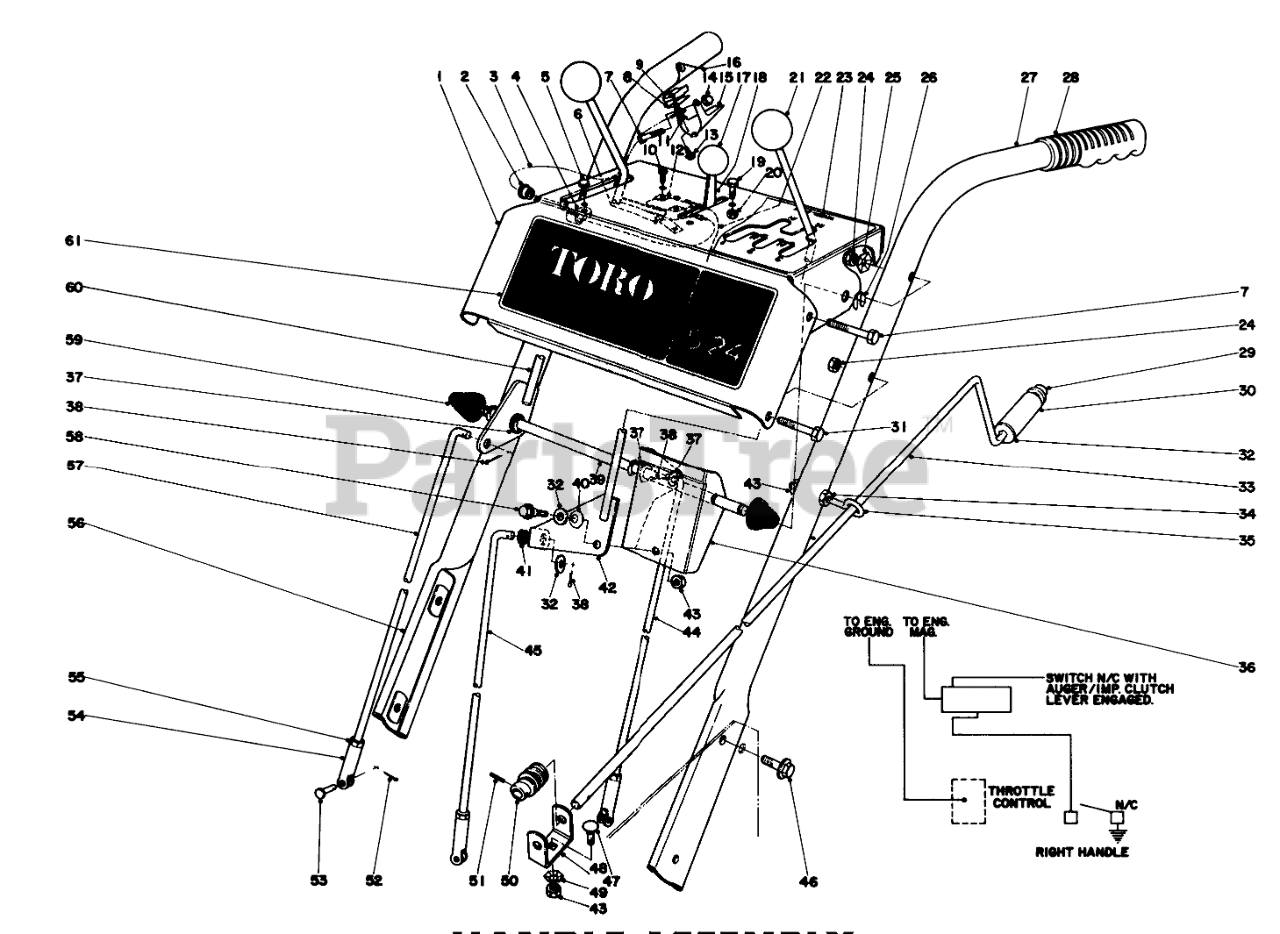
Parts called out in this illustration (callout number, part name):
1	Escutcheon
2	Snap Bushing
3	Wire Ass-y.
4	PLASTIC CLIP
5	SCREW-HWHTF
6	NUT-SPEED
7	SCREW-HH
8	INTERLOCK CONTACT
9	Insulator
10	SCREW-HEAD, PAN
11	WASHER INSULATOR
12	MICRO SWITCH
13	Screw
14	NUT-CAP
15	Safety Lever
16	INTERLOCK SPRING
17	CONTROL KNOB
18	Throttle Control (Model #31625)
19	Hex Hd. Sems
20	Nut
22	Wire Assembly
23	Decal Instruction
24	NUT-LOCK, CONE
25	Washer
26	RING-CLIP
27	Handle Left
28	Grip Handle
29	RETAINER-PUSH ON
30	CHUTE CONTROL GRIP
31	SCREW-HH
32	WASHER-FLAT
33	CHUTE CONTROL ROD
34	Nut
35	Eye Bolt
36	SHIFT BRACKET
37	WASHER-FLAT
38	PIN-COTTER
39	PIVOT ROD
40	7/16 SPRING WASHER
41	GROMMET-RUBBER
42	SHIFT LEVER WA
43	NUT-LOCK, CONE
44	TRACTION CONTROL ROD
45	SPEED SELECTOR ROD
46	SCREW-HHF
47	BOLT-CARR
48	WORM BRACKET
49	Washer Pyramidal
50	GEAR-WORM, CHUTE
51	PIN-SPRING
52	PIN-COTTER
53	PIN-CLEVIS
54	Clevis
55	NUT-HJ
56	Handle Right
57	Auger Control Rod
58	SHOULDER SCREW
59	CONICAL SPRING
60	LEVER WA
61	ESCUTCHEON DECAL
